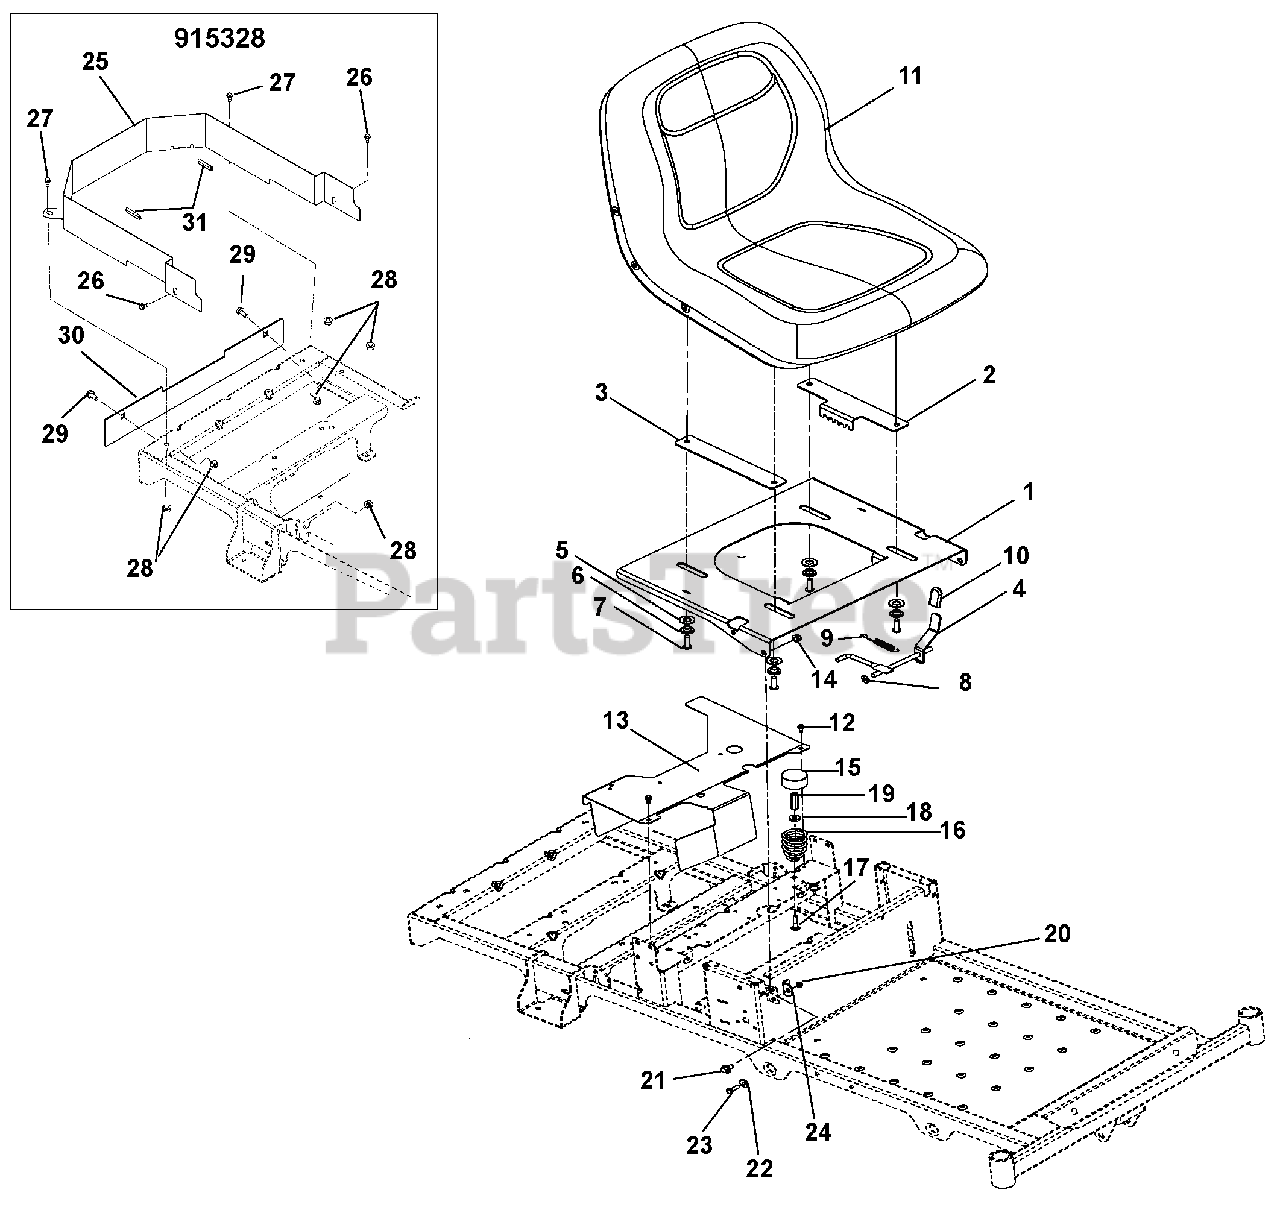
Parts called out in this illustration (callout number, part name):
1	Plate, Adjustable Seat
2	Plate, Adjustable Seat Track
3	Plate Adjustable Seat Slide
4	Weldment, Adjustable Seat Latch
5	Washer, Flat Steel .505 x 1.00 x .062
6	Bushing, Flange .32 x .500 x .344 x .880
7	Screw, Socket Head, Button Head .31-18 x 1.00
8	Push Nut 5/16
9	Weldment, Spring Tension .043 x .44 x 3.31, 5.8
10	Grip, Seat Lever, Grey
11	Seat, Milsco XB180 Grey
12	Screw, Tapping .25-20 x .50 Hex Washer Head Thread
13	Cover, Zoom CE Fan
14	Nut, .38-16 Locking Top Flange
16	Spring, Seat
17	Bolt, Round Head Square Neck .31-18 x 1.50
18	Washer, Flat Steel .328 x .87 x .179
19	Nut, Coupling 5/16-18 x 1.75
20	Nut, 5/16-18 Flange Nyloc
21	Bolt, Shoulder .375-16 x .135
22	Bushing, Flange .325 x .499 x .26 x .88
23	Bolt, Hex .31-18 x 1.00
24	Bracket, Seat Stop
25	Shield, ZT CE Reach-In
26	Bolt, Hex .38-16 x .75 Grade 5 YWCZ
27	Bolt, Hex .38-16 x 1.00 Grade 5 YWZC
28	Nut, Locking Center .38-16
29	Bolt, Round Head Square Neck .38-16 x .75 Grade 5 YWZC
30	Flange, Muffler Zoom CE
31	Edging, Molded
